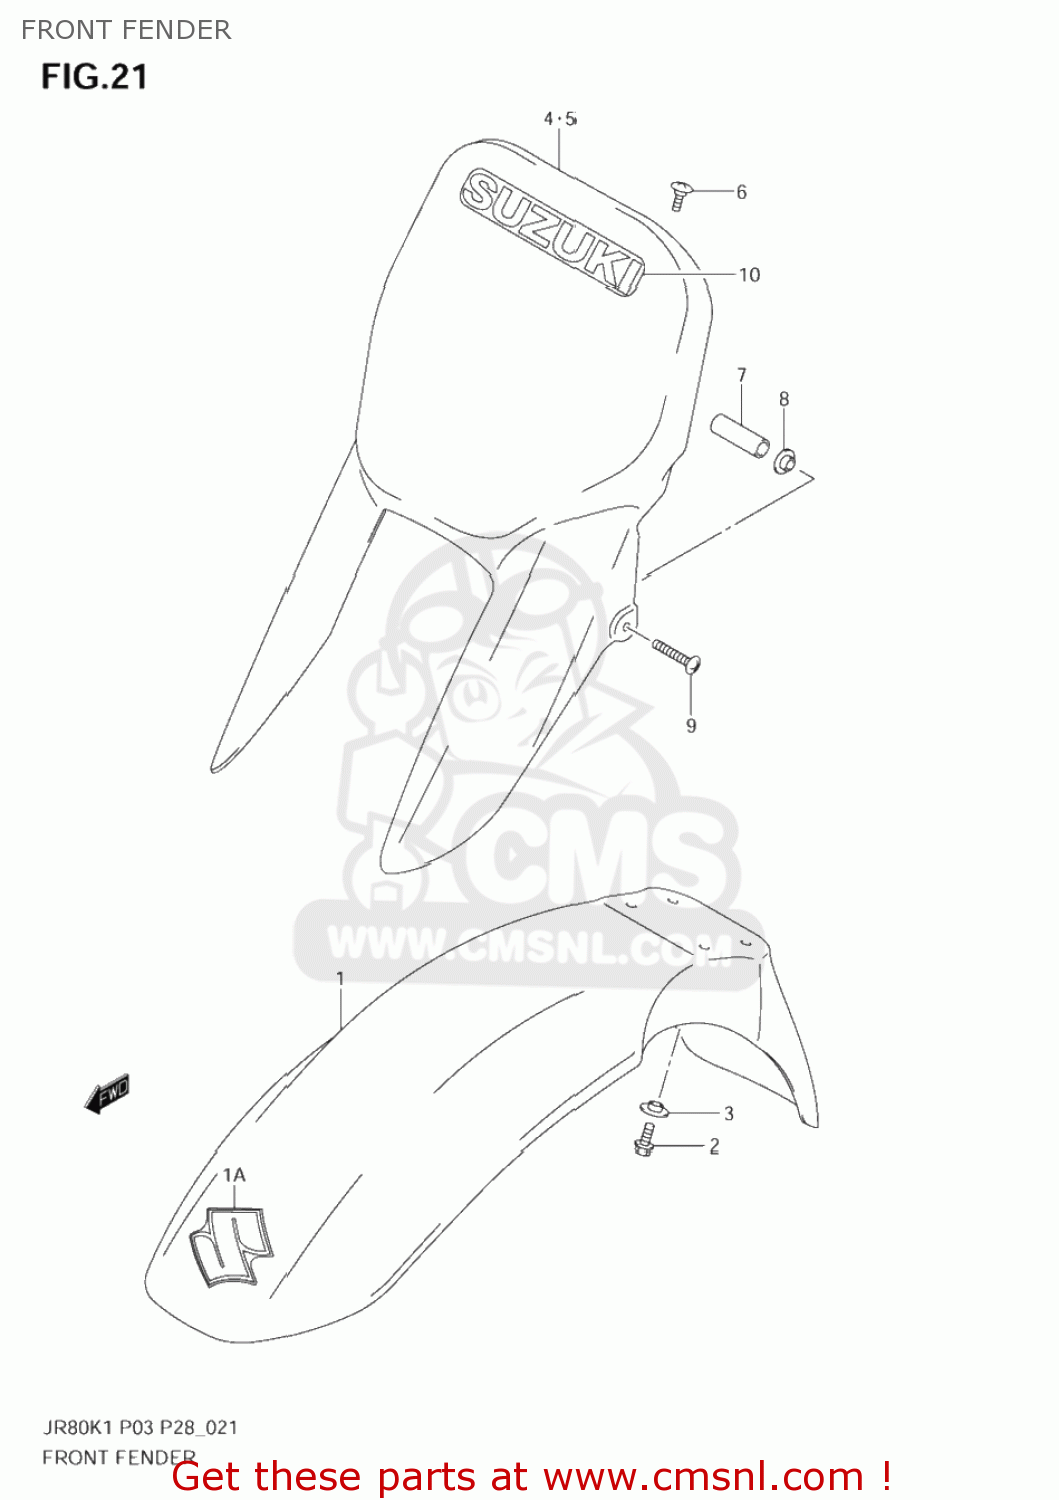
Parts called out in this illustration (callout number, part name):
1	FENDER,FR
1A	EMBLEM,S
2	BOLT
3	WASHER
4	PLATE,NUMBER FR
5	PLATE,NUMBER FR
6	SCREW(6X16)
7	SPACER(5.5X8X18)
8	WASHER
9	SCREW
10	EMBLEM,SUZUKI
